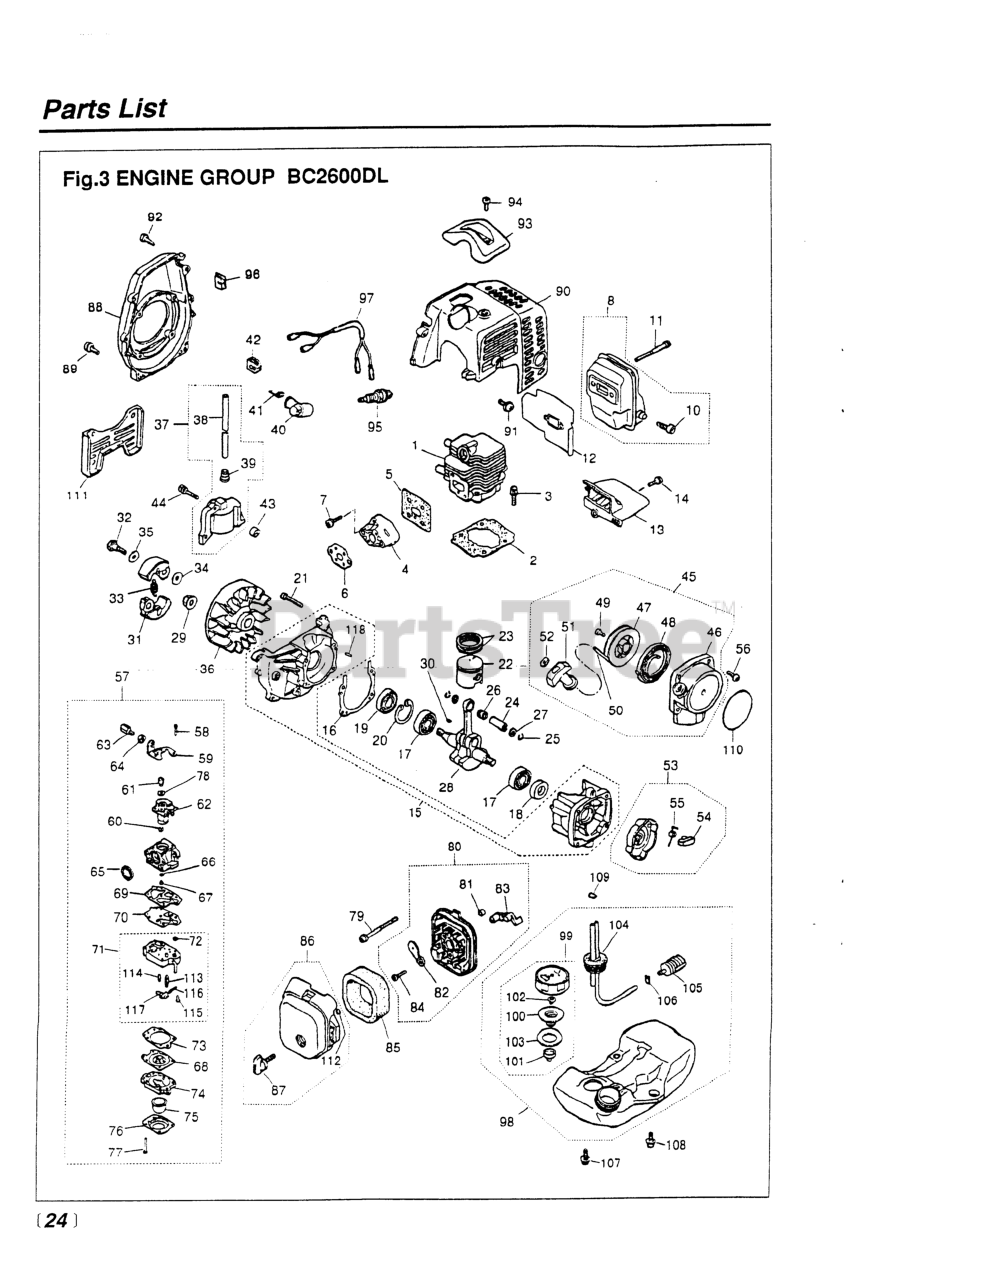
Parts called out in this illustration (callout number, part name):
1	CYLINDER
3	BOLT, M5 X 22
4	INSULATOR (USE -13163)
5	GASKET (RPLS -13120)
6	GASKET (REPLACES -13130)
7	SCREW, M5X20 (RPLS.1400-75510)
8	MUFFLER ASSY (RPLS 5501- )
10	ARRESTER (RPLS 5850-15140)
11	BOLT, M5 x 50
12	GASKET, MUFFLER (RPLS -15111)
14	SCREW, M4 X 16
15	CRANKCASE
16	GASKET (RPLS -21140)
17	BEARING
18	SEAL, OIL (RPLS 1100-21210)
19	SEAL, OIL (RPLS 1140-21220)
20	RING, SNAP, M28 x 1.2
21	BOLT, M5 X 30
22	PISTON
23	RING, PISTON
24	PIN, PISTON
25	RING, SNAP (RPLS 1101-41320)
27	WASHER
28	CRANKSHAFT (RPLS 1850-42000)
30	KEY
31	SHOE (RPLS 1100-51114)
32	BOLT
33	SPRING, CLUTCH (RPLS-51220)
34	WASHER, FLAT (USE 182303)
36	ROTOR
37	COIL ASSY (RPLS 5500-71200)
38	CORD
39	CAP
41	SPRING
42	GROMMET
43	SPACER (RPLS -71260)
44	BOLT
45	RECOIL ASSEMBLY
46	CASE
47	REEL
48	SPRING, SPIRAL
49	SCREW (RPLS -75150)
51	KNOB
52	PLATE, STOPPER
53	PULLEY ASSY (RPLS -75210)
54	RATCHET (RPLS 1850-75220)
55	SPRING, RETURN
56	SCREW, M4 X 16
57	CARBURETOR (WYJ-117)
58	SCREW
60	RING
61	SWIVEL
62	VALVE ASSY
63	SCREW, CABLE ADJUSTER
64	NUT, CABLE ADJUSTER
65	RING, PACKING
66	RING, O
67	JET
68	DIAPHRAGM (USE 4810-81260)
69	GASKET, PUMP
70	DIAPHRAGM
71	BODY, PUMP
73	GASKET, DIAPHRAGM
74	BODY, PURGE
75	PUMP, PRIMING
76	COVER, PUMP
77	SCREW
78	WASHER
79	SCREW, M5 X 55
80	BODY-A (RPLS -82101)
81	SLEEVE
82	PLATE, CHOKE (RPLS-82130)
83	LEVER, CHOKE
84	SCREW (REPLACES 50030272)
85	ELEMENT
87	KNOB (RPLS -82220)
88	COVER, FAN (RPLS-31110)
89	SCREW, M5X20 (RPLS.1400-75510)
90	COVER, ENGINE (RPLS -32111)
91	SCREW, M5 x 12
92	SCREW, HOUSING
93	GUARD, PLUG
94	SCREW,M5 X 14 (RPLS 1400-15510
97	CORD COMP (RPLS -73200)
101	HOLDER, CAP
102	VALVE (NLA WHEN OUT)
103	PACKING
104	PIPE COMPLETE
105	FILTER (RPLS 1850-85300)
106	CLIP (REPLACES 2841-31280)
107	SCREW
108	SCREW W/ WASHER
109	CLIP
110	LABEL, RECOIL (RPLS -91120)
111	STAND
112	RING
113	VALVE, INLET
114	SPRING, METERING LEVER
115	SCREW, METERING LEVER PIN
116	PIN, METERING LEVER
117	LEVER
118	PIN
